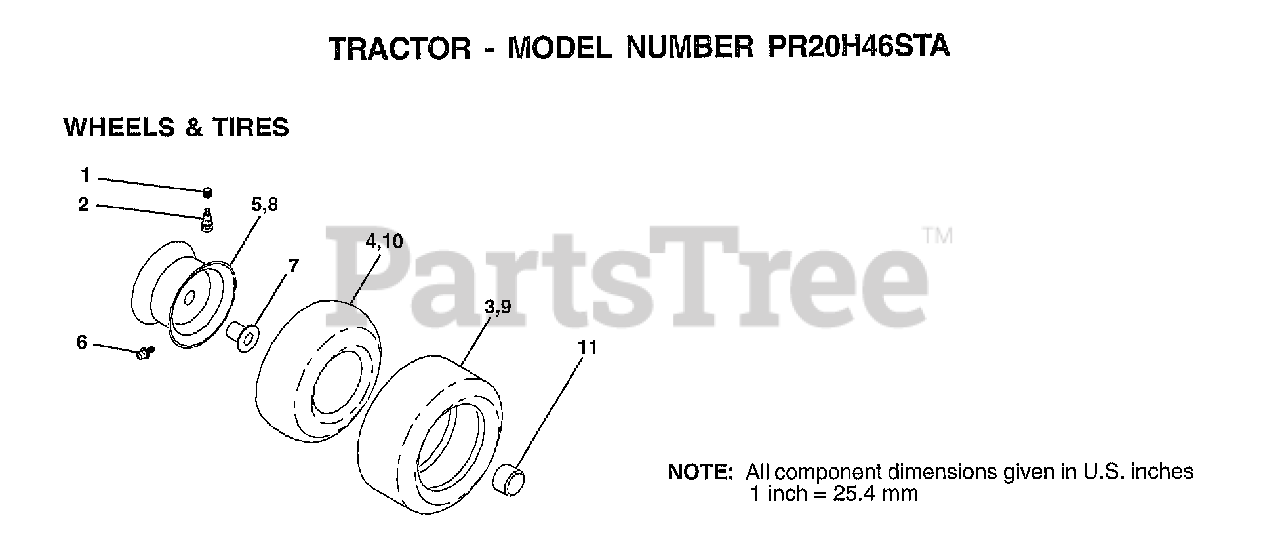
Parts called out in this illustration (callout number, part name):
1	VALVE CAP
2	VALVE STEM LT
3	TIRE
4	TUBE.5.3/4.5/6
5	RIM.FRONT.6.YELLO
6	FITTING LT
7	"FLANGE, BEARING"
9	TIRE
10	TUBE.18X9.5-8
11	HUB CAP
